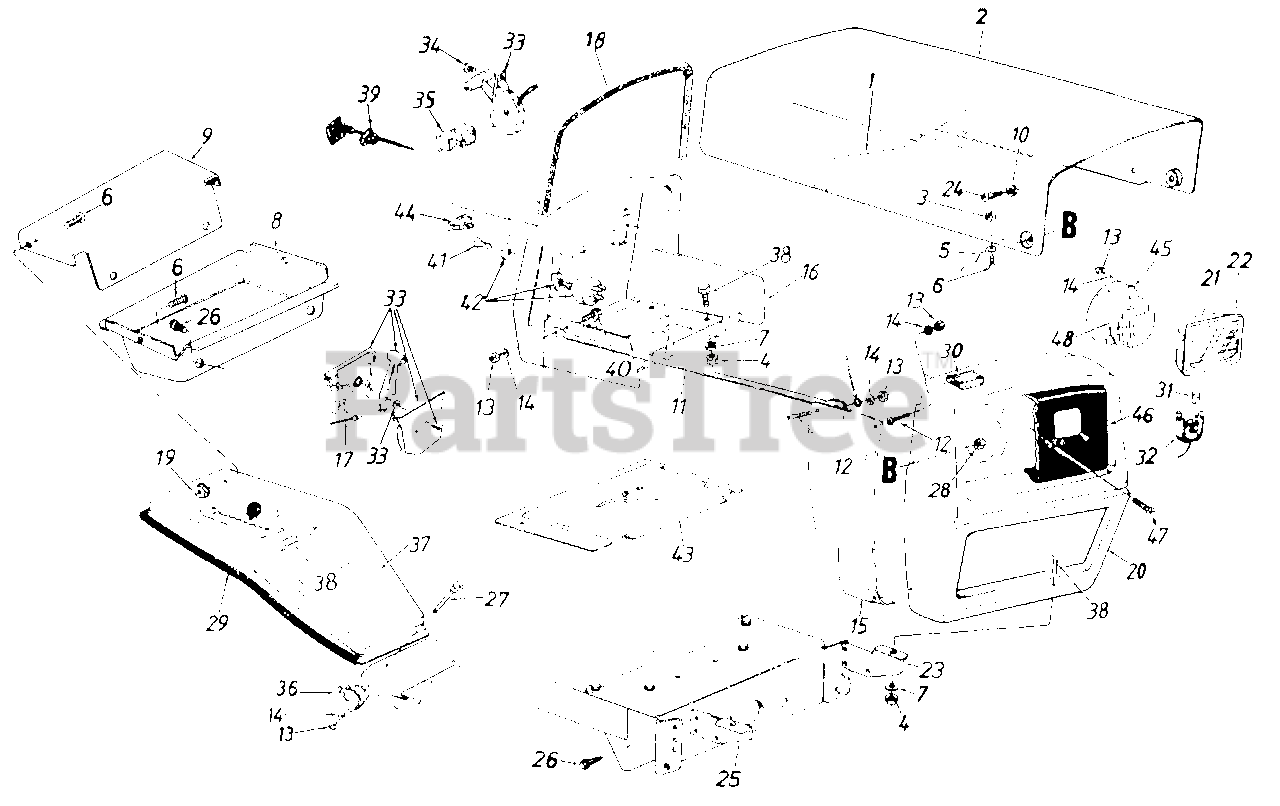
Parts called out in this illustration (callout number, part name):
1	Hood Spring
4	Hex Nut 5/16-18 Thd.
5	Hood Stop 7" Lg.
6	Truss Hd. Scr. #10-24 x '/2"
7	L-Wash. 5/16" I.D.
8	Tool Tray
11	Grille Support Rod
12	Truss Hd. Scr. 1/4-20 x .75"
13	Hex Nut 1/4-20 Thd.
14	L-Wash. 1/4" I.D.
15	R.H.-Grille Side Panel
17	Throttle Control Wire-B&S
18	Molding Strip 27" Lg.
19	Hex Sems Nut #10-24 Thd.
22	Headlight Lens
23	Mounting Brkt.
24	Shld. Bolt .375" Dia. x .125"
27	Carriage Bolt 1/4-20 x 2.0" Lg.
28	L-Nut 1/4-28 Thd.
29	Trim Strip-57" Lg.
30	Foam Strip 3/8 x 1-1/8 x 1'/2
31	Head Lamp
32	Twist Lock Lamp Socket
33	Throttle Box Ass'y.
34	Truss Mach. AB-Tap Scr. #10 x .5" Lg.
35	Ammeter
36	Fender Clamp
39	Choke Control 29" Lg.
40	Hex Bolt 1/4-20 x .62" Lg.
41	Ignition Key
42	Ignition Switch
43	Shift Cover
44	Light Switch
45	Headlight Retainer
46	Bezel
47	Oval C-Sunk Scr. 1/4-20 x 1.5"
48	Round Headlight
